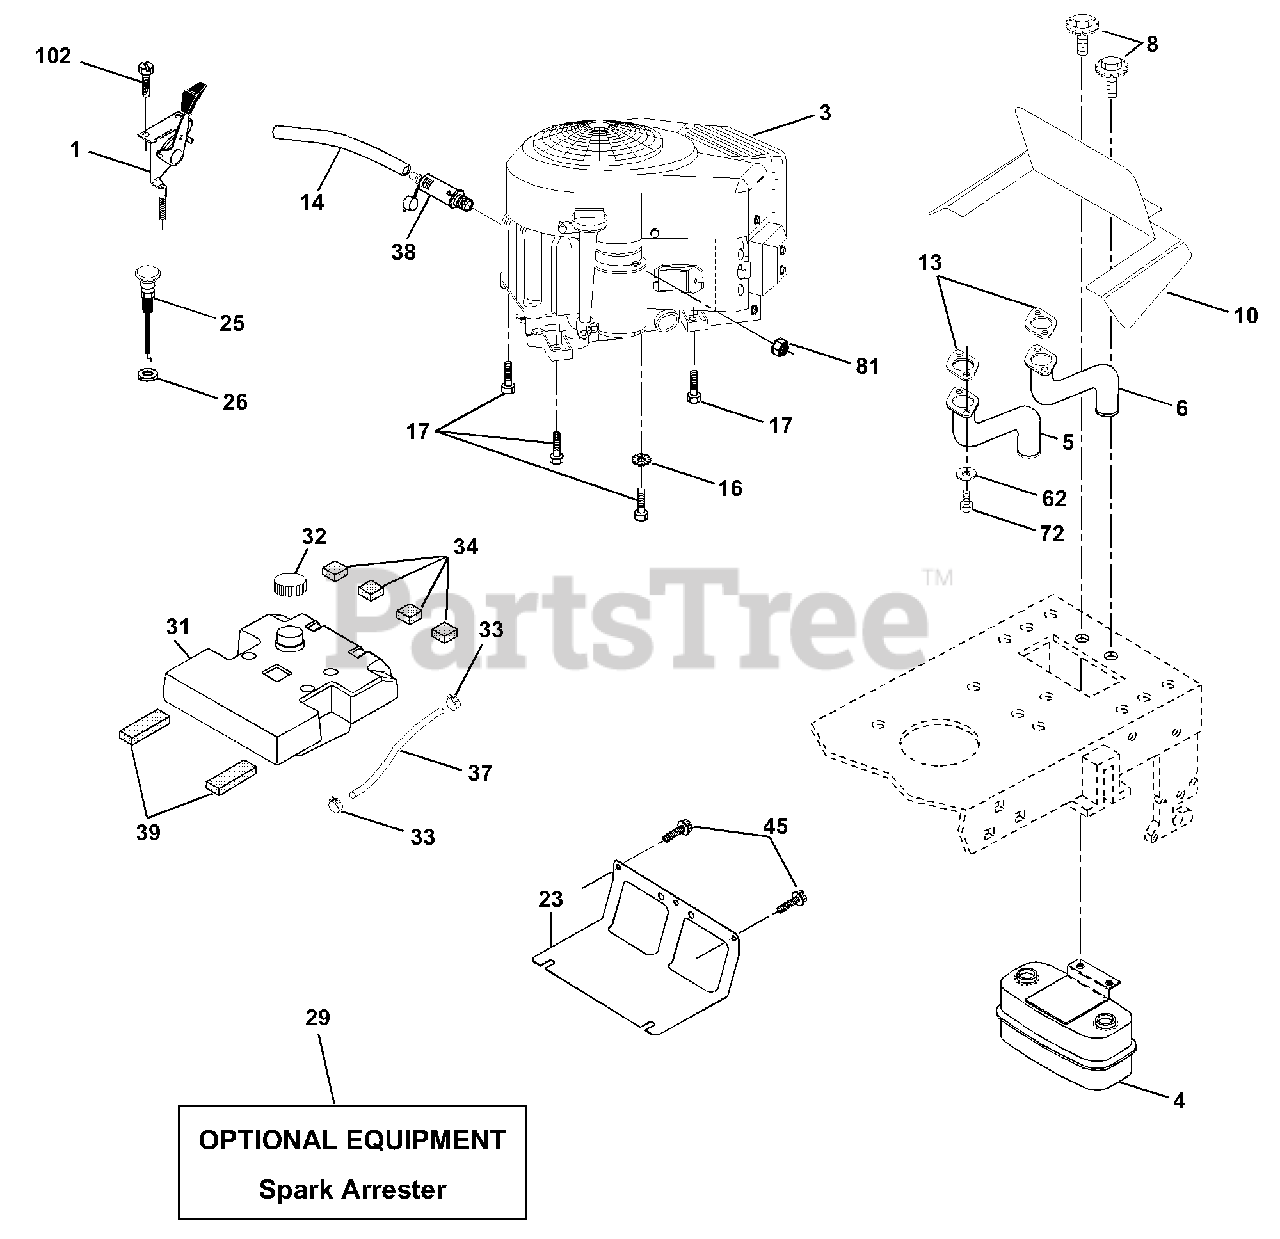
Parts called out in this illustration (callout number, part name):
1	Control Throttle
2	Screw Hex Thd Cut 1/4-20x5/8 T
4	Muffler Asm Twin Lo-Tone
5	Pipe Exhaust LH Intek
6	Pipe Exhaust RH Intek
8	Bolt 5/16-18 UNC x 3/4 w/Sems
10	Shield Browning Intek II
13	Muffler Gasket
14	Tube Drain Oil Easy
16	Washer Lock Ext Tooth 3/8
17	Screw Thdrol 3/8-16 x 1-1/2
23	Shield Heat
25	Choke Control
26	Nut, Keps 3/8-24 UNF
29	Kit Spark Arrestor (Flat Scrn)
31	Tank Fuel 3 50 Rear
32	Cap Asm Fuel W/sym Vented
33	Clamp Hose Black
34	Pad, Spacer
37	Line Fuel
38	Plug Drain Oil Easy
39	Pad, Idler
45	Screw Hexwsh Thdr 3/8-16 x 3/4
62	Washer Lock 5/16
72	Screw Hex Hd Cap 5/16-18 x 3/4
81	Nut Keps Hex 1/4-20 UNC
102	Screw Hw Hd Hi-Lo #13-16 x 3/4
